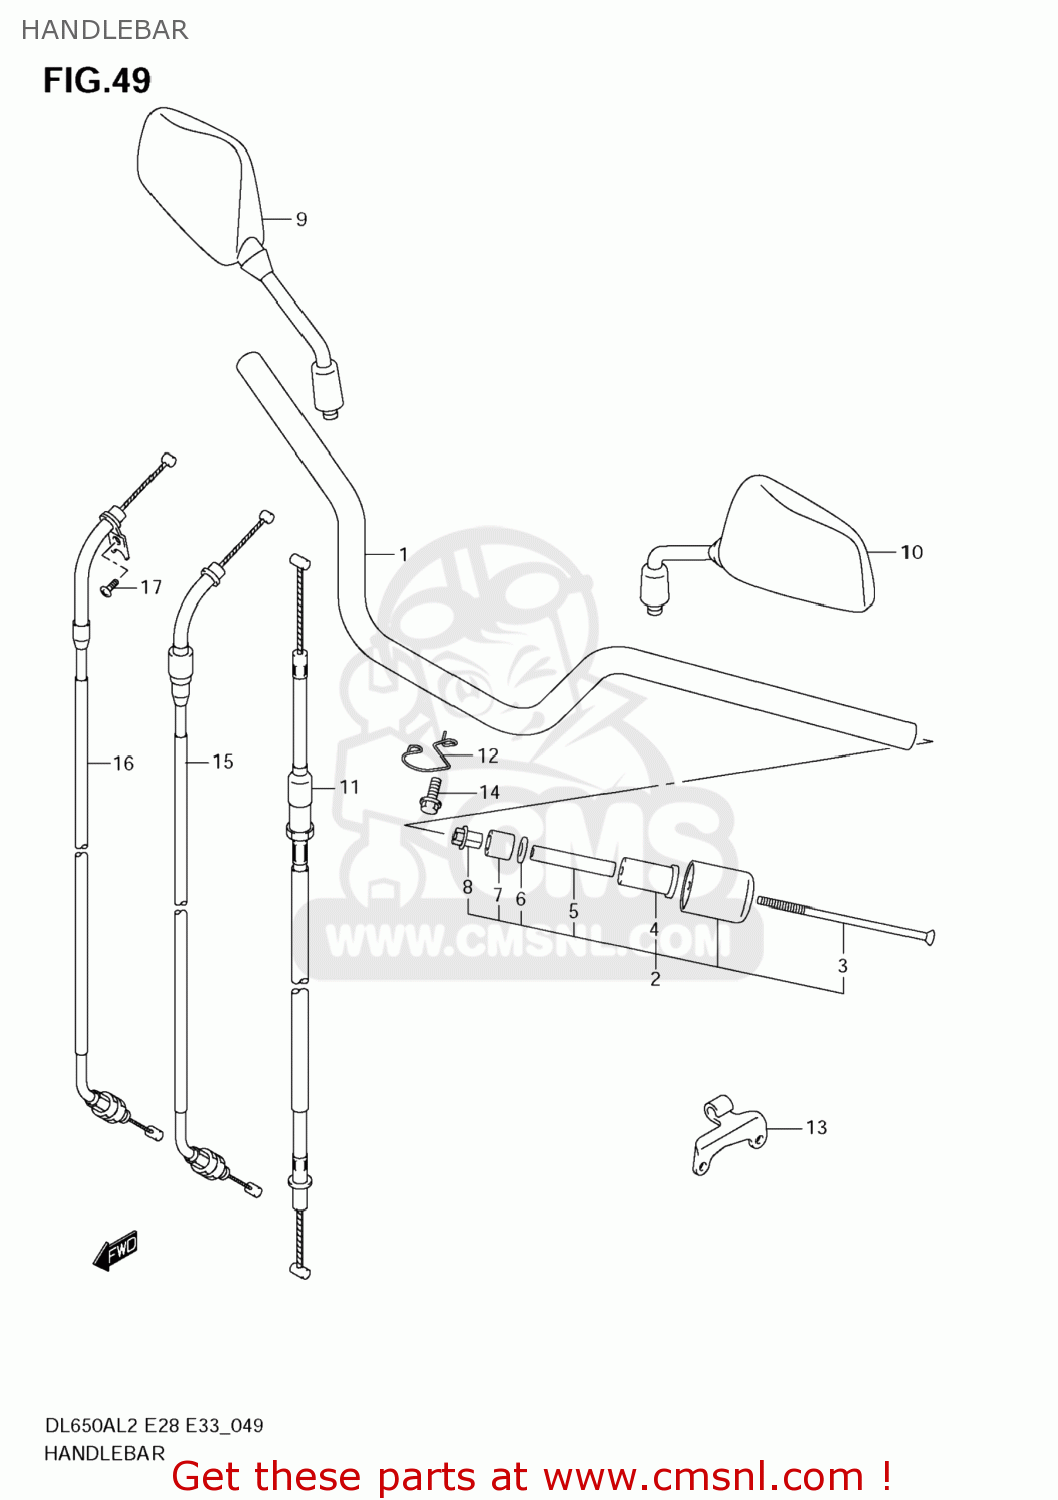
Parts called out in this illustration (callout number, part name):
1	HANDLEBAR(SILVER)
2	BALANCER SET,HANDLEBAR
3	SCREW(6X110)
4	EXPANDER
5	SPACER,EXPANDER
6	WASHER(6.5X16X4)
7	EXPANDER,HANDLE BALANCER
8	NUT,HANDLE BALANCER
9	MIRROR ASSY,RR VIEW,R
10	MIRROR ASSY,RR VIEW,L
11	CABLE ASSY,CLUTCH
12	GUIDE,CLUTCH CABLE
13	STOPPER,CLUTCH CABLE
14	BOLT
15	CABLE ASSY,THROTTLE NO.1
16	CABLE ASSY,THROTTLE NO.2
17	SCREW(5X10)
